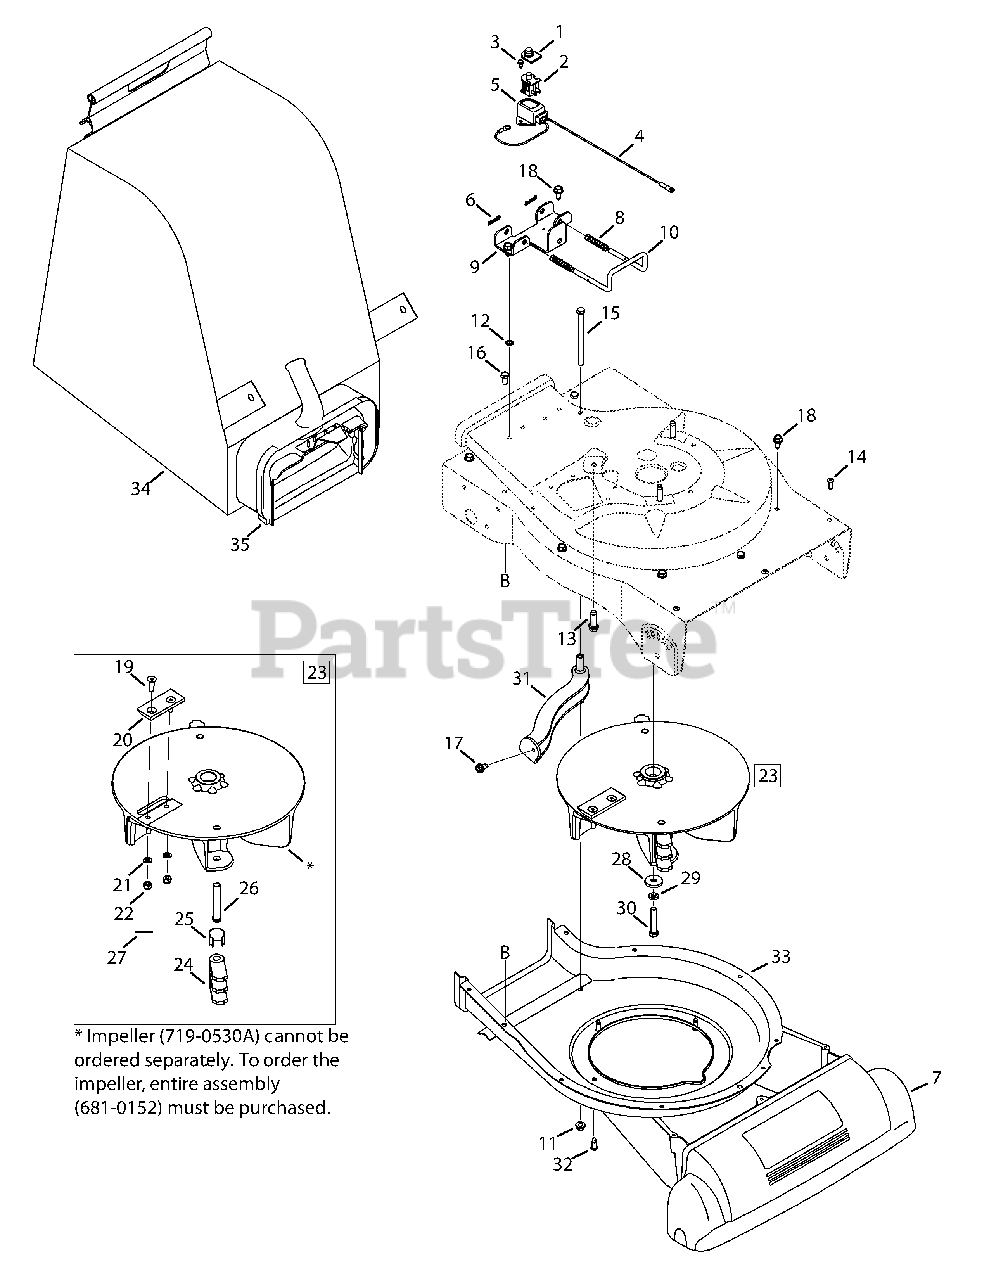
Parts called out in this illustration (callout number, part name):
1	Switch Cover
2	Safety Switch
3	Hex Washer Screw, #10-16 x.50
4	Wire Harness
5	Safety Switch Cover
6	Cotter Pin
7	Nozzle Cover
8	Compression Spring
9	Mounting Bracket
10	Lock Rod
11	Flange Lock Nut, 5/16-18
12	External Lock Washer 5/16
13	Hex Washer Screw 3/8-16 x 1.25
14	Screw, #12-16 x .750
15	Hex Cap Screw 5/16-18 x 4.5
16	Hex Cap Screw 5/16-18 x.625
17	Screw, 5/16-18 x.500
18	Screw, 5/16-12 x.75
19	Hex Screw 5/16-24 x 1.0
20	Chipper Blade
21	Lock Washer 5/16
22	Hex Lock Nut 5/16-24
23	Impeller Assembly
24	Flail Blade
25	Pin Clip
26	Clevis Pin
27	Spiral Pin
28	Flat Washer.375 ID x 1.25 OD
29	Lock Washer 3/8
30	Hex Cap Screw 3/8-24 x 2.0
31	Screen Assembly
32	Shoulder Screw, .30 x .46
33	Lower Housing
34	Bag Assembly
35	Chute Assembly
